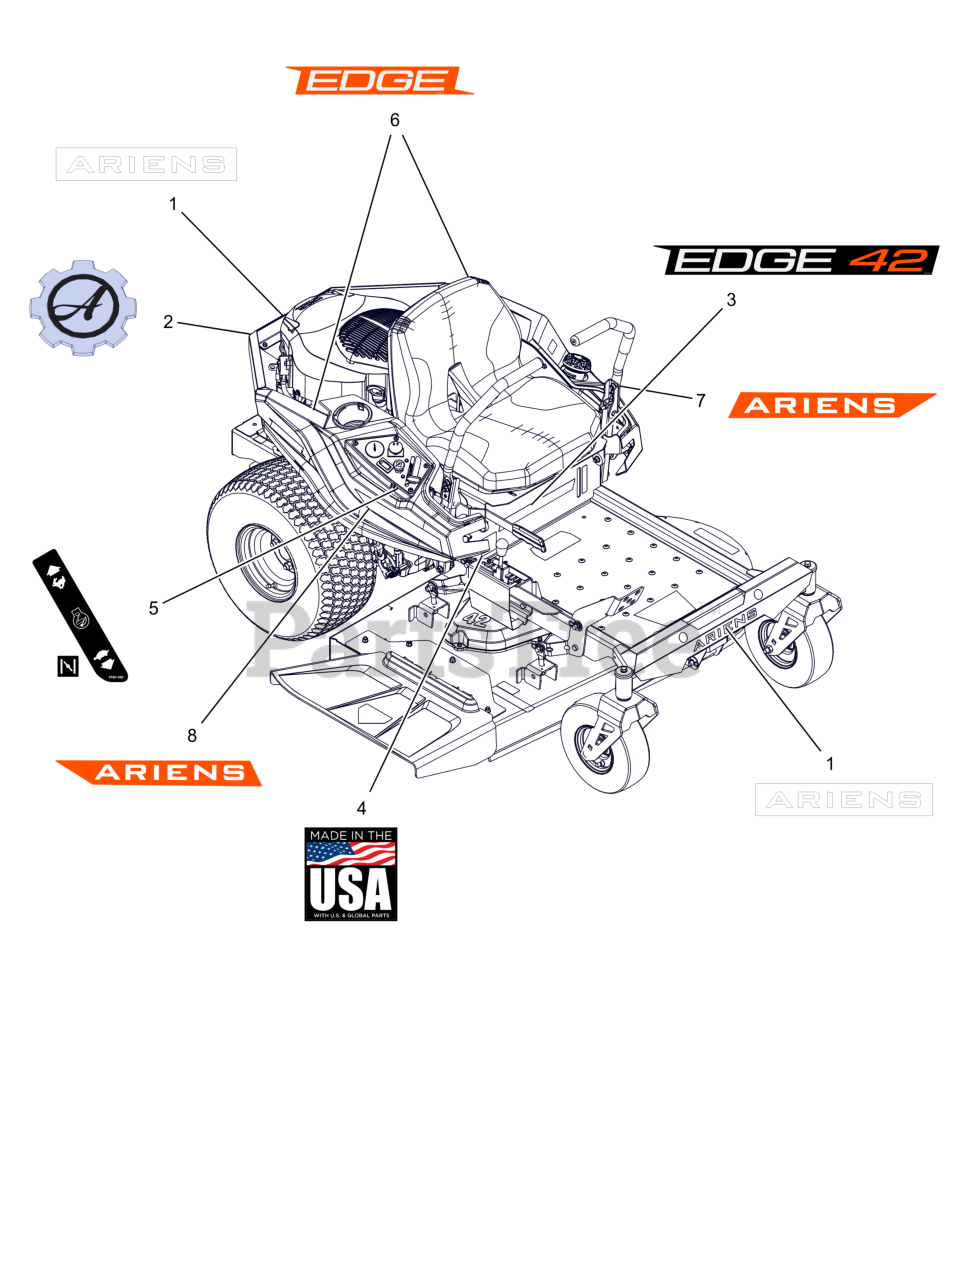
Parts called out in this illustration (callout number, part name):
1	DECAL - ARIENS 9.625"
2	DECAL, ARIENS-GEAR BADGE -THK
3	DECAL, EDGE 42 - KICKPLATE
4	DECAL, MADE IN USA
5	DECAL, SPEED CONTROL
6	DECAL, EDGE FENDER
7	DECAL, ARIENS FENDER LH
8	DECAL, ARIENS FENDER RH
